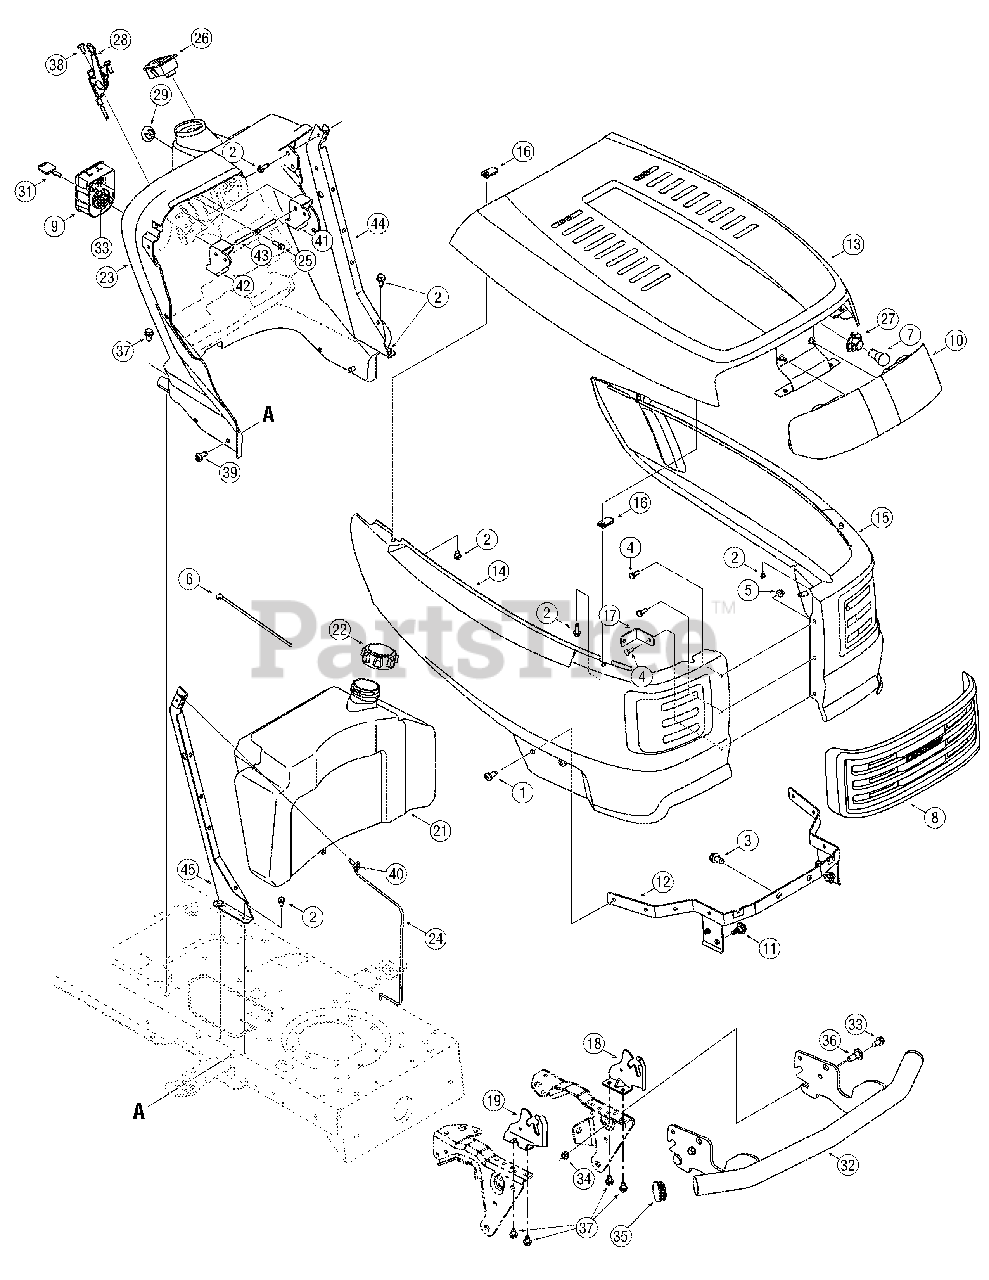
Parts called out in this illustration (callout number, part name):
1	Screw, 5/16-18, .375
2	Screw, 1/4-20, 0.500
3	Screw, 5/16-18, 0.625
4	Screw, 1/4-20, 0.620
5	Flange Lock Nut, 1/4-20
6	Cable Tie, 3/16 x .05 x 7.4
7	Headlamp, 12V
8	Troy-Bilt Grill Insert
9	Switch Housing
10	Lens
11	Screw, Shldr, .43 x .29, 5/16-18
20	Cable Tie, 34.75
21	Fuel Tank, 3 gal. TB
22	Fuel Tank Cap
23	Dash Panel, 8/9 Style w/ Man PTO
24	Gas Tank Support Rod
25	Screw, 1/4-15, .750
26	Ammeter Monitor Indicator
27	Lamp Socket
28	Throttle/Choke Control, 25.0
29	Choke Plug
30	Module, Ign. Switch (No RMC)
30	Module, Ignition Switch (RMC)
31	Key
31	Key w/ Plastic Grip
33	Screw, 5/16-12, 0.750
34	Flange Lock Nut, 3/8-16
35	Bumper Cap
36	Shoulder Bolt, 3/8-16
37	Screw, 5/16-18, 0.500
38	Screw, 1/4-14, 0.625
39	Screw, 5/16-18, 0.750
40	Screw, 1/4-20, 0.750
41	Dash Brake Lever
42	Dash Cruise Lever
43	Bent Lever Rod
